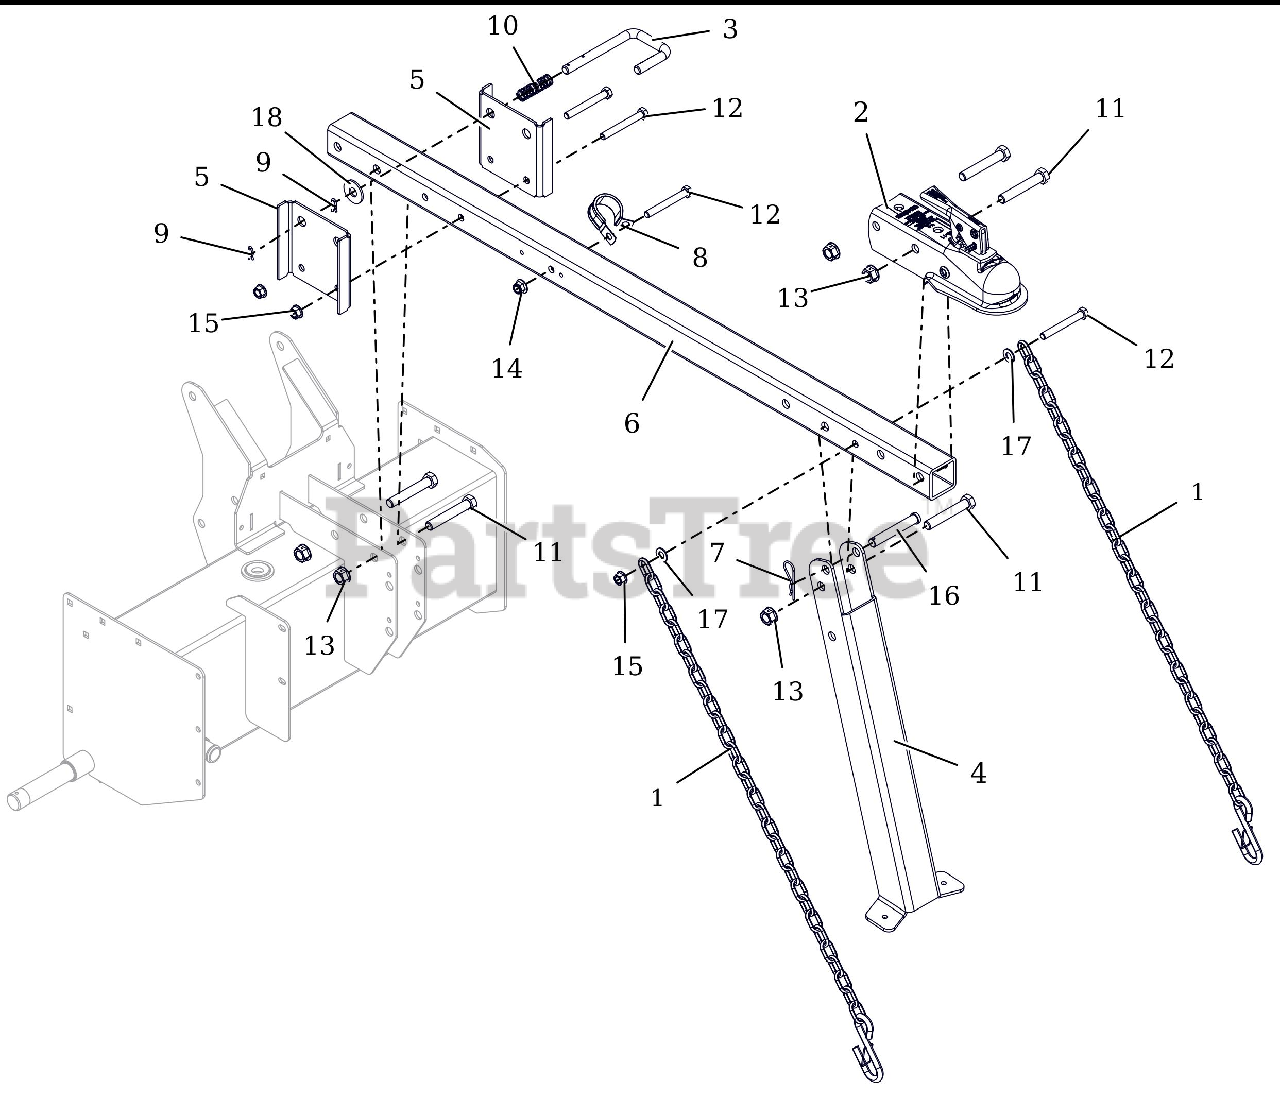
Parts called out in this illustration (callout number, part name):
1	CHAIN, SAFETY 3/16"-30LINK
2	COUPLER-BALL 2.000"
3	LOCK, BEAM
4	LEG SUPPORT-FRONT
5	GUIDE, LOCK DOWN
6	DRAWBAR TUBE W/SAFETY DECAL-22
7	HAIRPIN, #7 CLIP .094X2.31 YWZ
8	CLAMP, CUSHIONED STEEL 1.25
9	CLIP, SPRING
10	SPRG, COMP .058X.65X2.13 WLD15
11	@BLT-HEX .50-13X3.00 GR5 YWZC
12	@BLT-HEX .38-16X3.00 GR5 YWZC
13	NUT-LK-CTR-FLG .50-13 YWZC
14	@NUT-LK-NYL-FLG .38-16 YWZC
15	@NUT-LK-TOP-FLG .38-16 YWZC
16	PIN-CLEVIS .500 X 3.250
17	@WSHR-FL-STL.406X.812X.065 YWZ
18	@WSHR-FL-STL.563X1.38X.109YWZC
